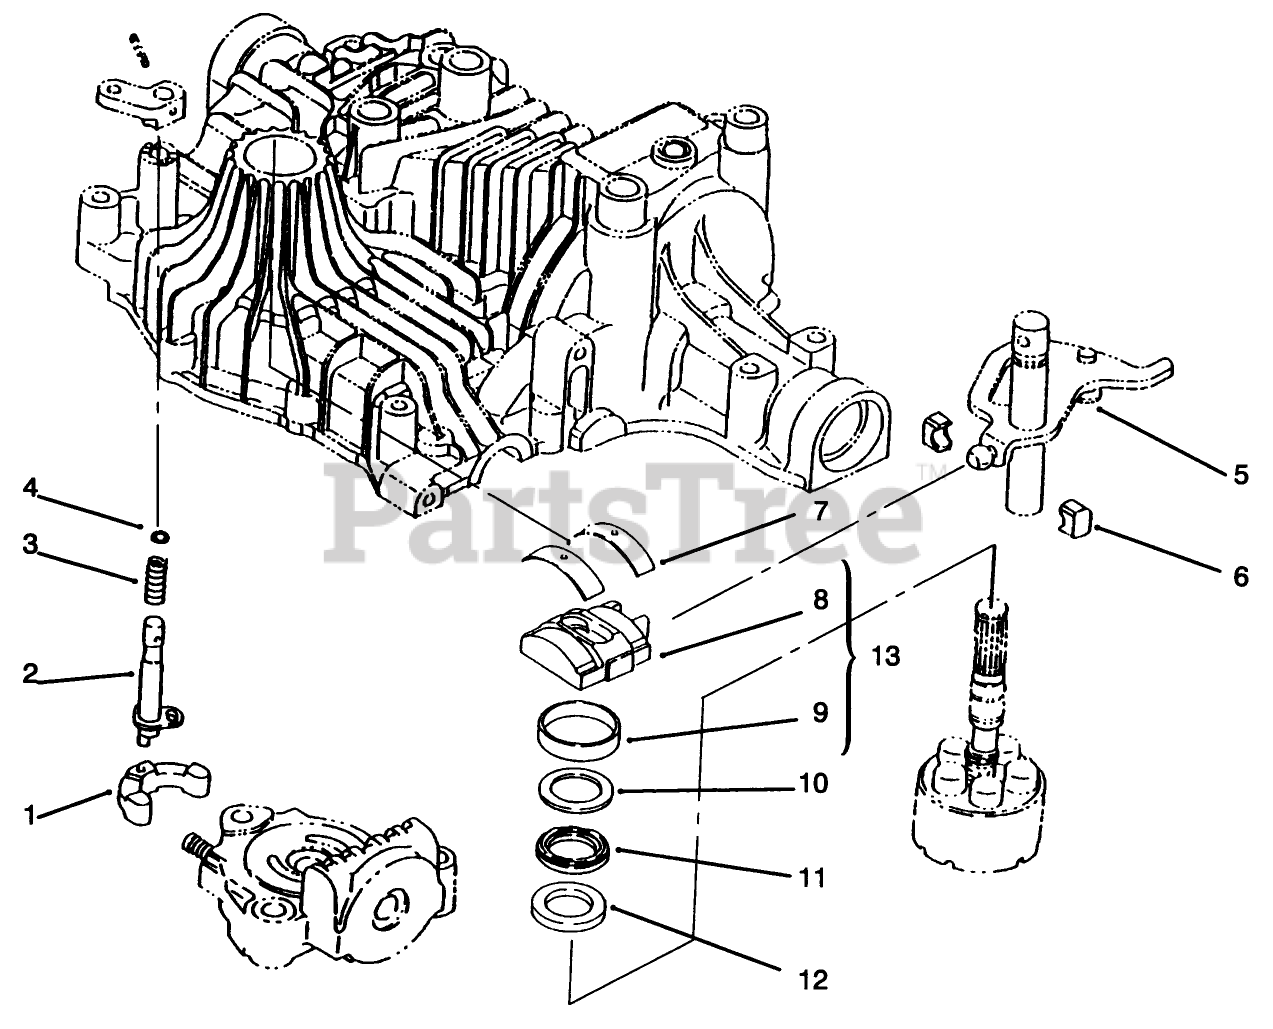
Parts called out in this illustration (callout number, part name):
2	SHAFT-BYPASS
3	SPRING
4	O-RING
5	BLOCK ASM
6	Block-Shift
7	THRUST METAL
8	Plate-Swash
9	Bushing-Swashplate
10	PLATE-THRUST
11	BEARING
12	PLATE - THRUST
13	PLATE-SWASH
